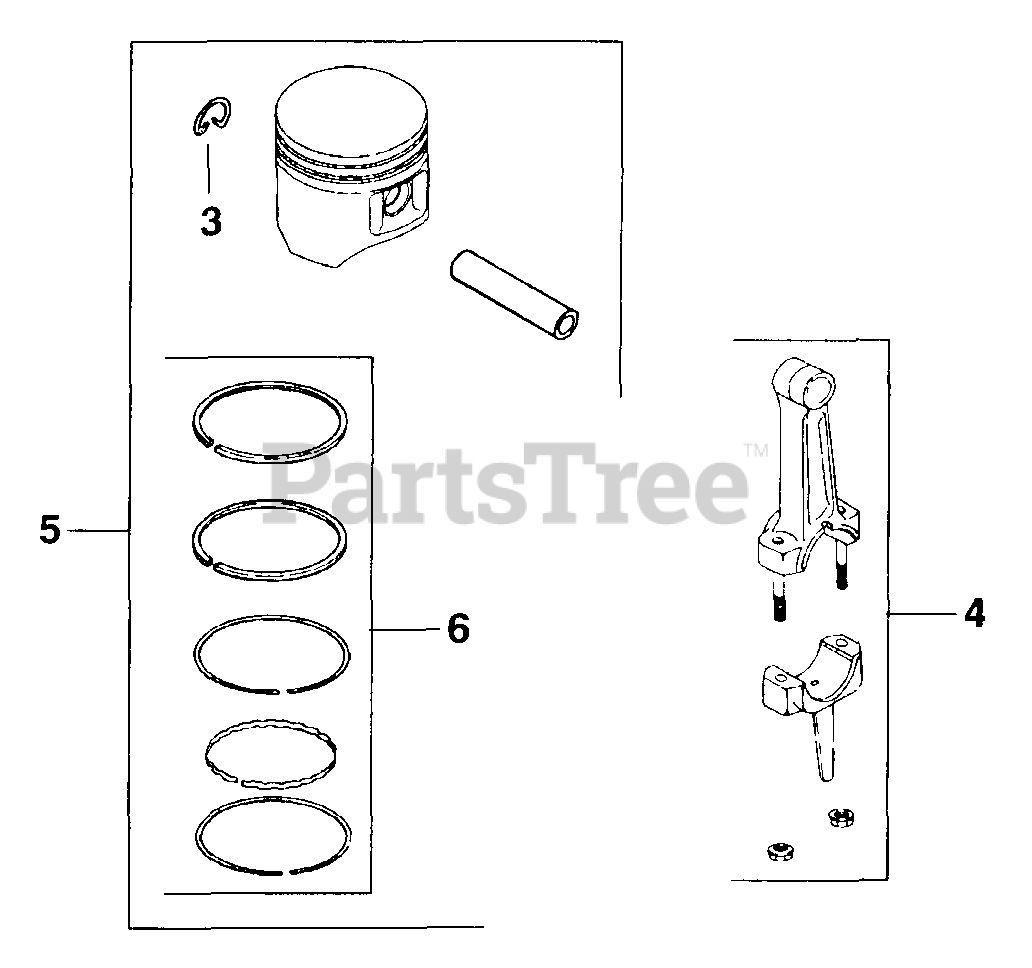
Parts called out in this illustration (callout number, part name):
5	KIT, PISTON W/RING SET STD - DISCONTINUED
5	PISTON W/RING SET .003 - DISCONTINUED
5	PISTON W/RING SET .010 - DISCONTINUED
5	KIT, PISTON W/RING SET .020
5	KIT, PISTON W/RING SET .030 - DISCONTINUED
6	RING SET STD. - DISCONTINUED
6	RING SET .010
6	RING SET .020
6	RING SET .030
